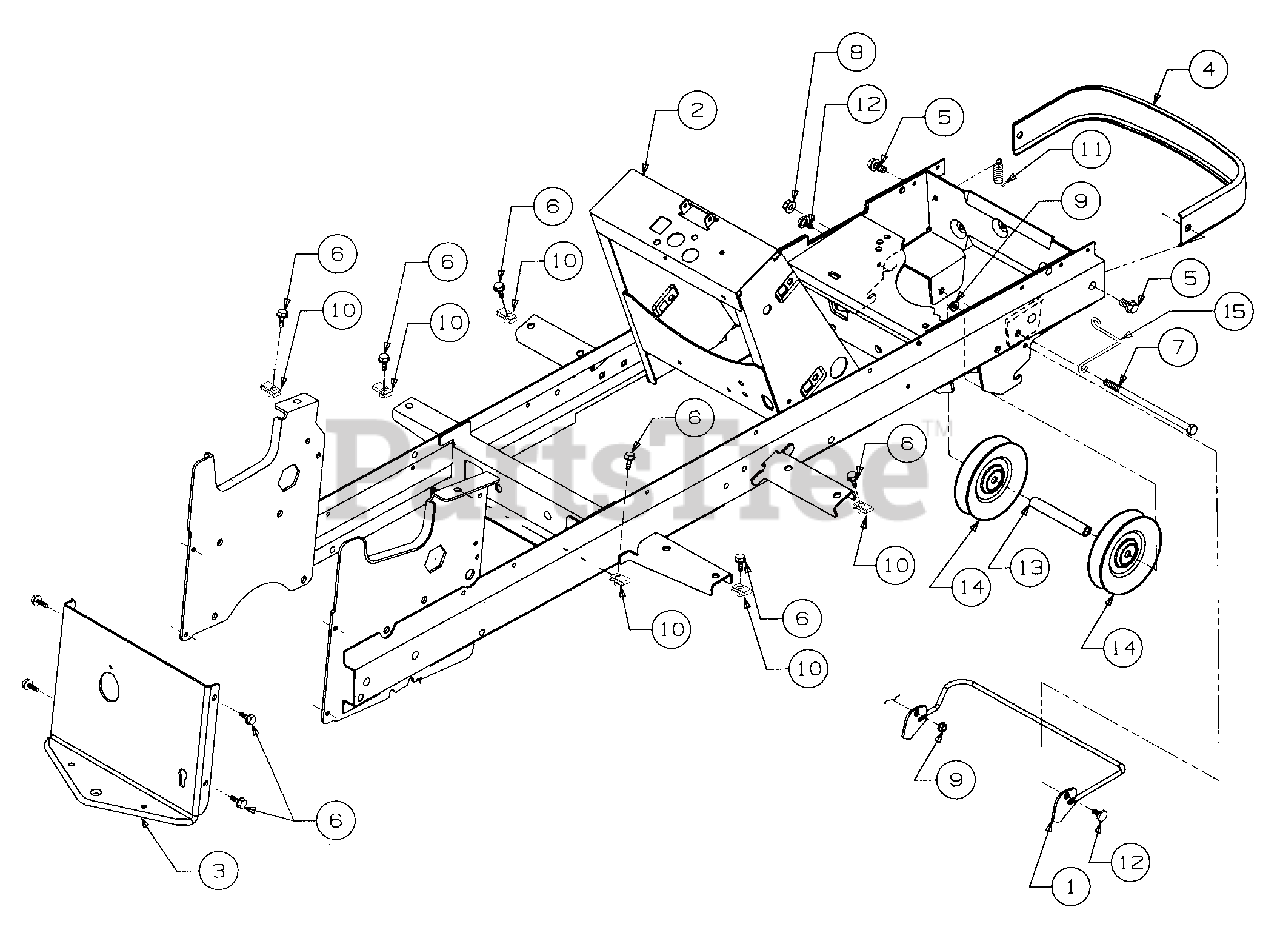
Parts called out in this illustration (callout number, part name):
1	Rod, Quick Attach
3	Drawbar
4	Bumper
5	Screw, Hex Wsh Hd Tapp 3/8-16 x .75
6	Screw, Hex Wsh Hd Tap 5/16-18 x .75
7	Screw, Hex Cap, 3/8-16 x 7.0
8	Nut, Hex Flange Lock, 3/8-16
9	Nut, Hex Flange Lock, 1/4-20
10	U-Nut, 5/16-18
11	Spring, Latch
12	Bolt, Shoulder
13	Spacer, Idler, .407 x .720 x 4.38
14	Pulley, Idler
15	Belt Guide
